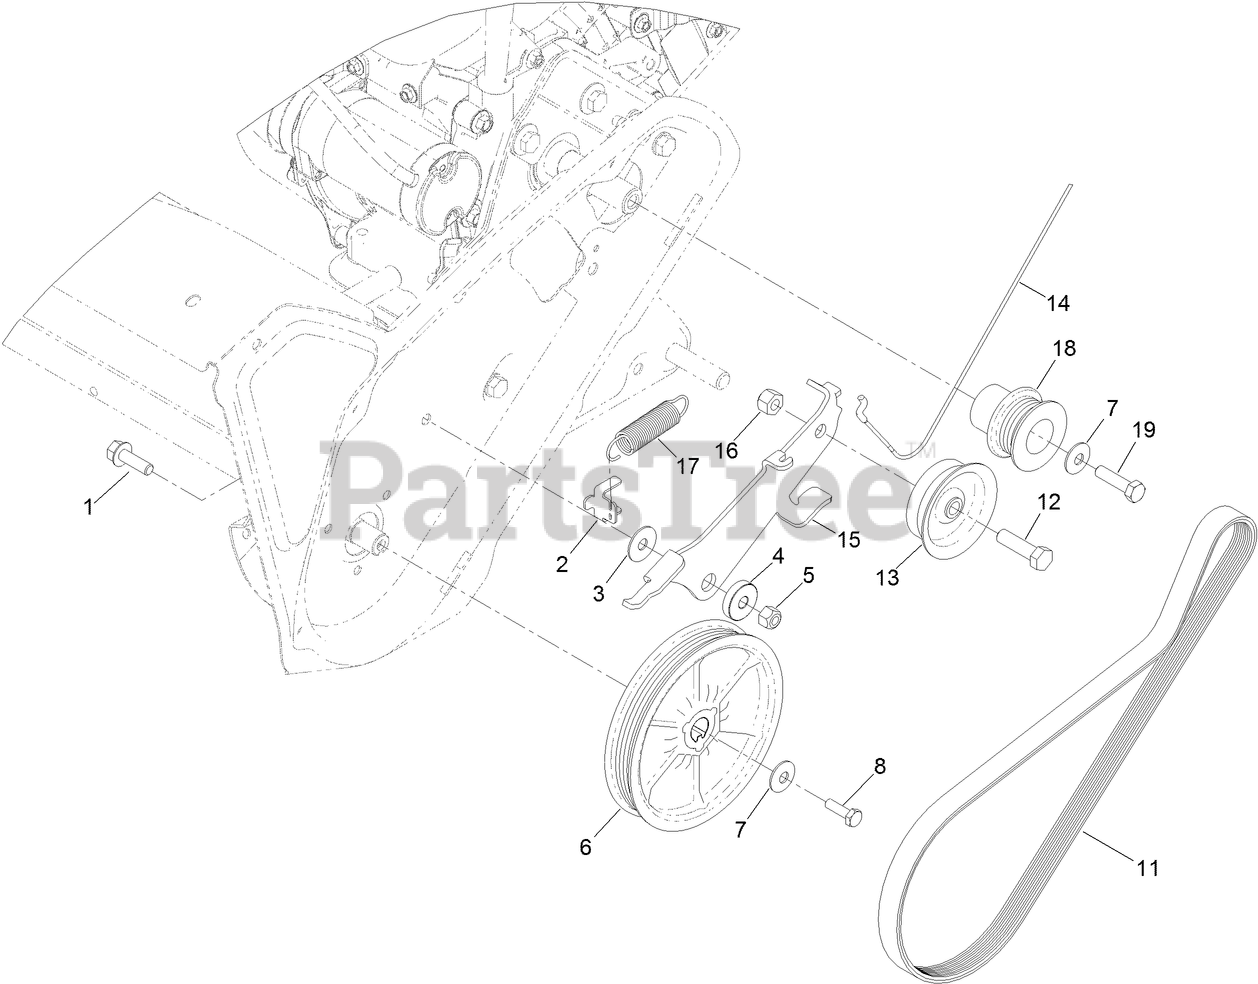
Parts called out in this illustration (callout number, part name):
1	SCREW-HHF
2	CLIP-SPRING
3	WASHER
4	BUSHING-PIVOT
5	NUT-LOCK, NI
6	PULLEY-ROTOR
7	WASHER-BELLEVILLE
8	SCREW-HH
11	BELT-POLY
12	SCREW-HH
13	PULLEY-IDLER, FLAT
14	CABLE-CLUTCH
15	ARM-IDLER
16	NUT-LOCK, CONE
17	SPRING-EXTENSION
18	PULLEY-ENGINE
19	SCREW-HH
